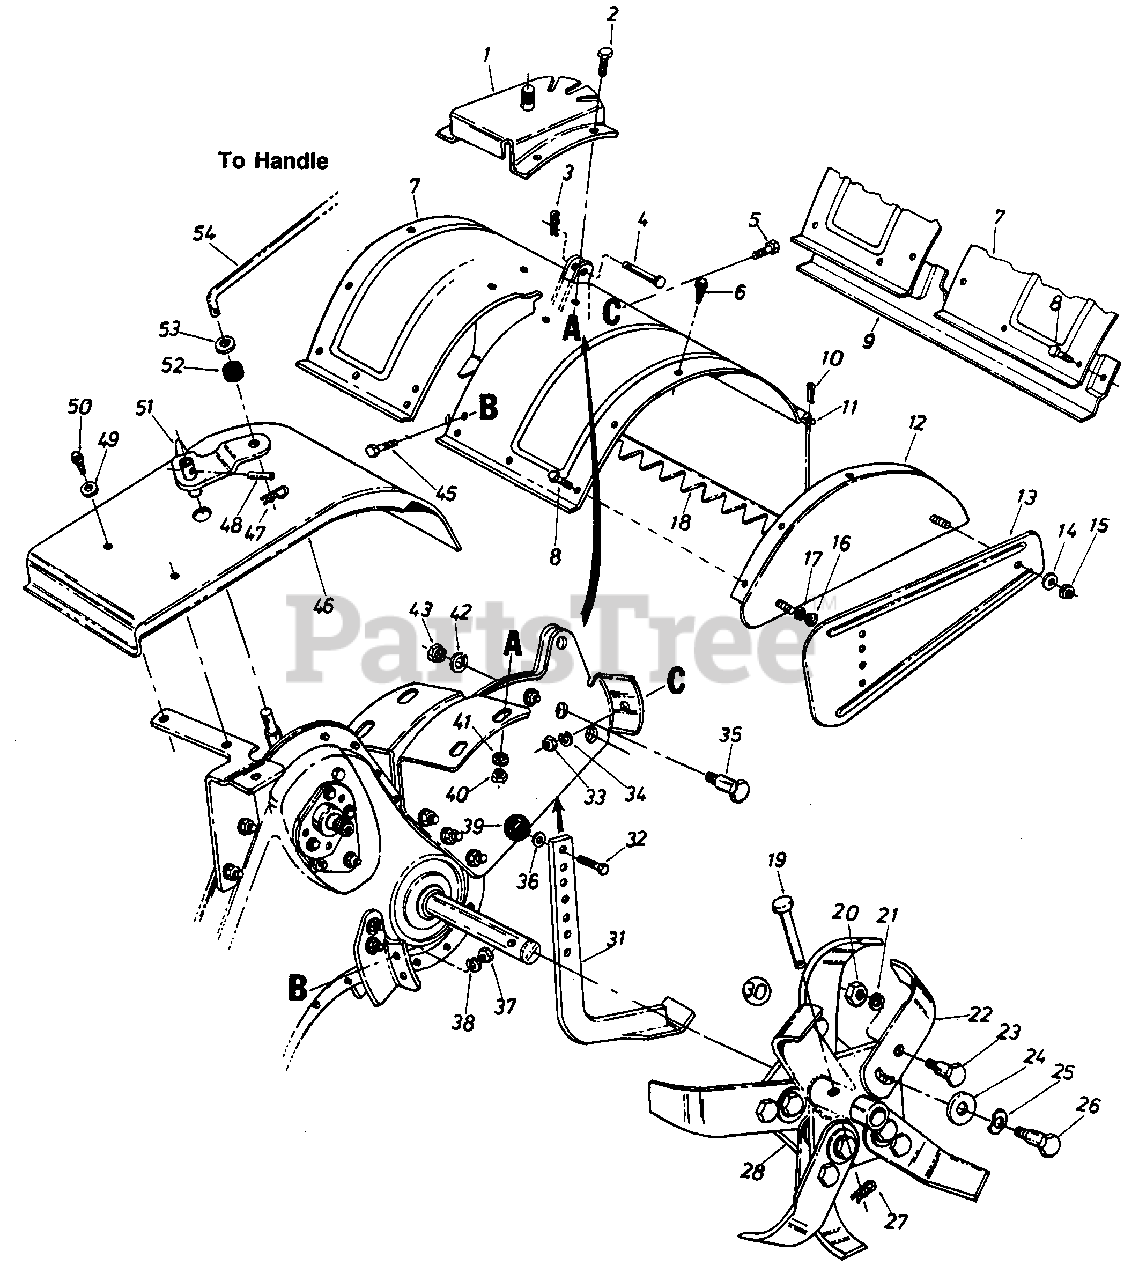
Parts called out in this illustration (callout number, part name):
3	Intern. Cotter Pin 5/16" Dia.
4	Clevis Pin .375" Dia.
5	Hex Bolt 5/16-18 x .75" Lg.
6	Hex Wash. Tap Scr.
9	Bracket Reinforcement-18
10	Cotter Pin 3/32" Dia. x .75" Lg .
11	Tiller Flap Rod
12	End Cover Ass'y.
15	Hex Nut 5/16-18 Thd.
16	Hex Nut 5/16-18 Thd.
17	L-Wash. 5/16" I.D.
19	Clevis Pin .375" Dia.
20	Hex Nut 3/8-24 Thd.
21	L-Wash. 3/8" I.D.-H.D.
22	13" Dia. Articulating Tine
23	Shld. Bolt 1/2" Dia. x .175
24	Fl-Wash. .51" I.D. x 1.50" O.D.
25	Bell-Wash. .515" I.D. x 1.14" O.D.
26	Shld. Bolt 1/2" Dia. x .320
27	Intern. Cotter Pin
28	Tine Adapter Ass'y. 18"
30	Tine Ass'y. Comp. 18"
31	Depth Bar Ass'y.
32	Hex Bolt 3/8-16 x .75" Lg.*
33	Hex Nut 5/16-18 Thd.*
34	L-Wash. 5/16" I.D.*
35	Shld. Bolt 1/2" I.D. x .62" Lg.
36	Fl-Wash. 3/8" I.D. x 5/8" O.D.
37	Hex Nut 5/16-18 Thd.*
38	L-Wash. 5/16" I.D.*
39	Ball Knob
40	Hex Nut 3/8-16 Thd.*
41	L-Wash. 3/8" I.D.*
42	L-Wash. 3/8" I.D.*
43	Hex Nut 3/8-16 Thd.*
45	Hex Bolt 5/16-18 x .75" Lg.*
46	Shift Cover
47	Intern. Cotter Pin 5/16" Dia.
48	Spring Roll Pin 3/16" Dia. x 1.00" Lg.
49	Fl-Wash. .281" I.D. x .62" O.D.
50	Hex Wash. Self-Tap Scr. '/4-20 x .50" Lg.
51	Shifting Crank Ass'y. D x 2.05
52	Rubber Washer .33" I.D. x .87" O.D.
53	Fl-Wash. .400" I.D. x 1.250" O.D.
54	Control Rod .33" Dia. x 37" Lg.
